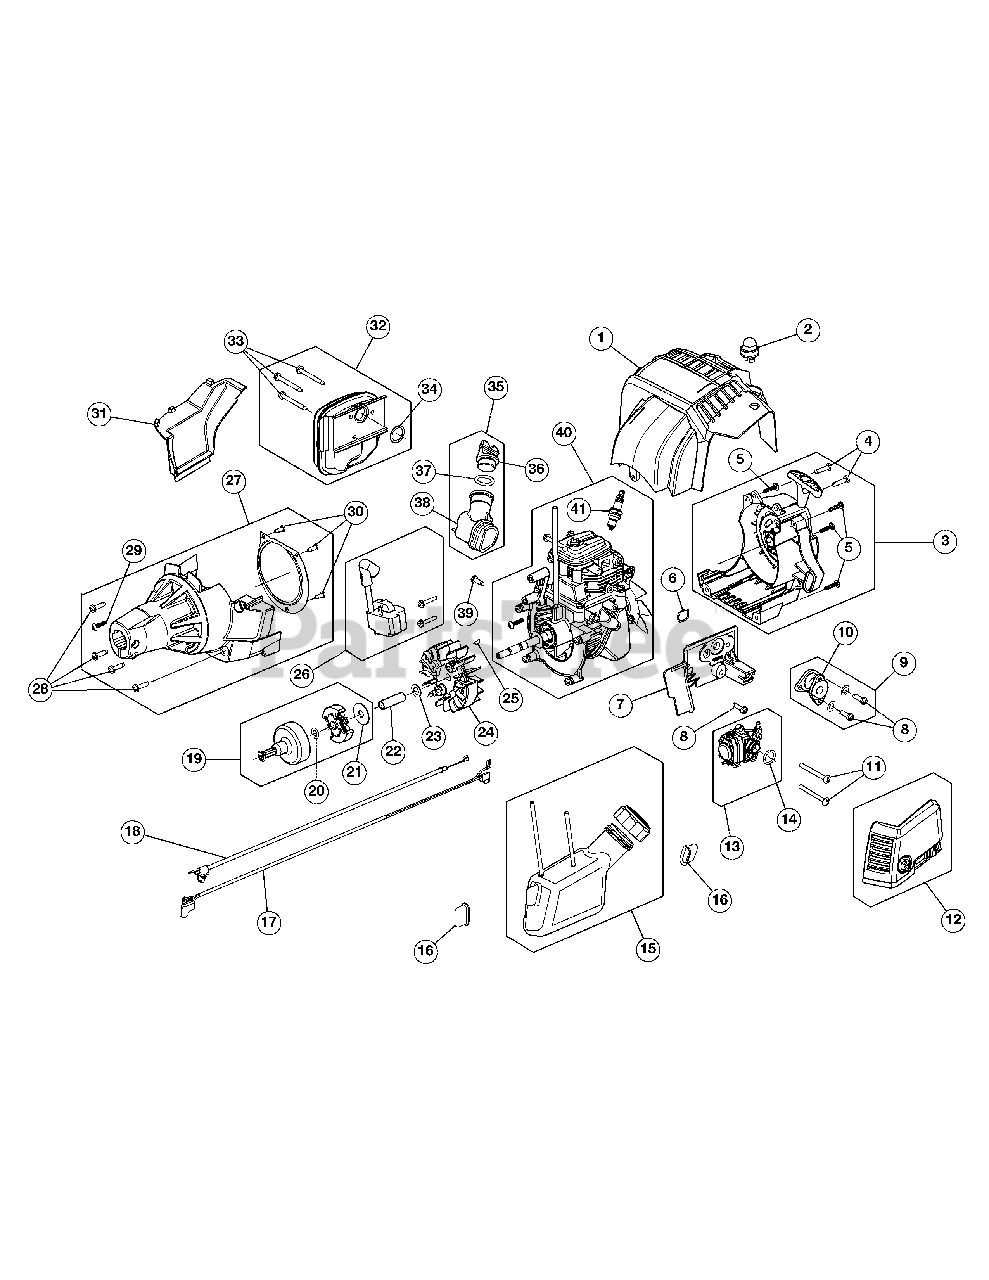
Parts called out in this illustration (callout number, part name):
1	Top Housing
2	Air Purge Primer
3	Starter Housing Assembly (Incl. 4 & 5)
6	O-Ring
7	Intake Port
8	Screw
9	Boot Assembly (Incl. 8 & 10)
10	Boot
12	Air Cleaner Assembly
12	Air Filter
13	Carburetor Assembly (Incl. 14)
15	Fuel Tank Assembly
16	Fuel Tank Pad
17	Lead Wire
18	Throttle Cable
19	Clutch Assembly (Incl. 20 & 21)
20	Thrust Washer
21	Clutch Washer
22	Spacer
23	Washer
24	Flywheel
26	Module Assembly
27	Clutch Cover Assembly (Incl. 28-30)
30	Screw
31	Rear Engine Cover
32	Muffler Assembly (Incl. 33 & 34)
33	Screw
34	Muffler Gasket
35	Oil Fill Tube Assembly (Incl. 36-38)
36	Oil Fill Plug
37	O-Ring
38	Oil Fill Tube
39	Screw
40	Shortblock Assembly (Incl. 41)
41	Spark Plug
